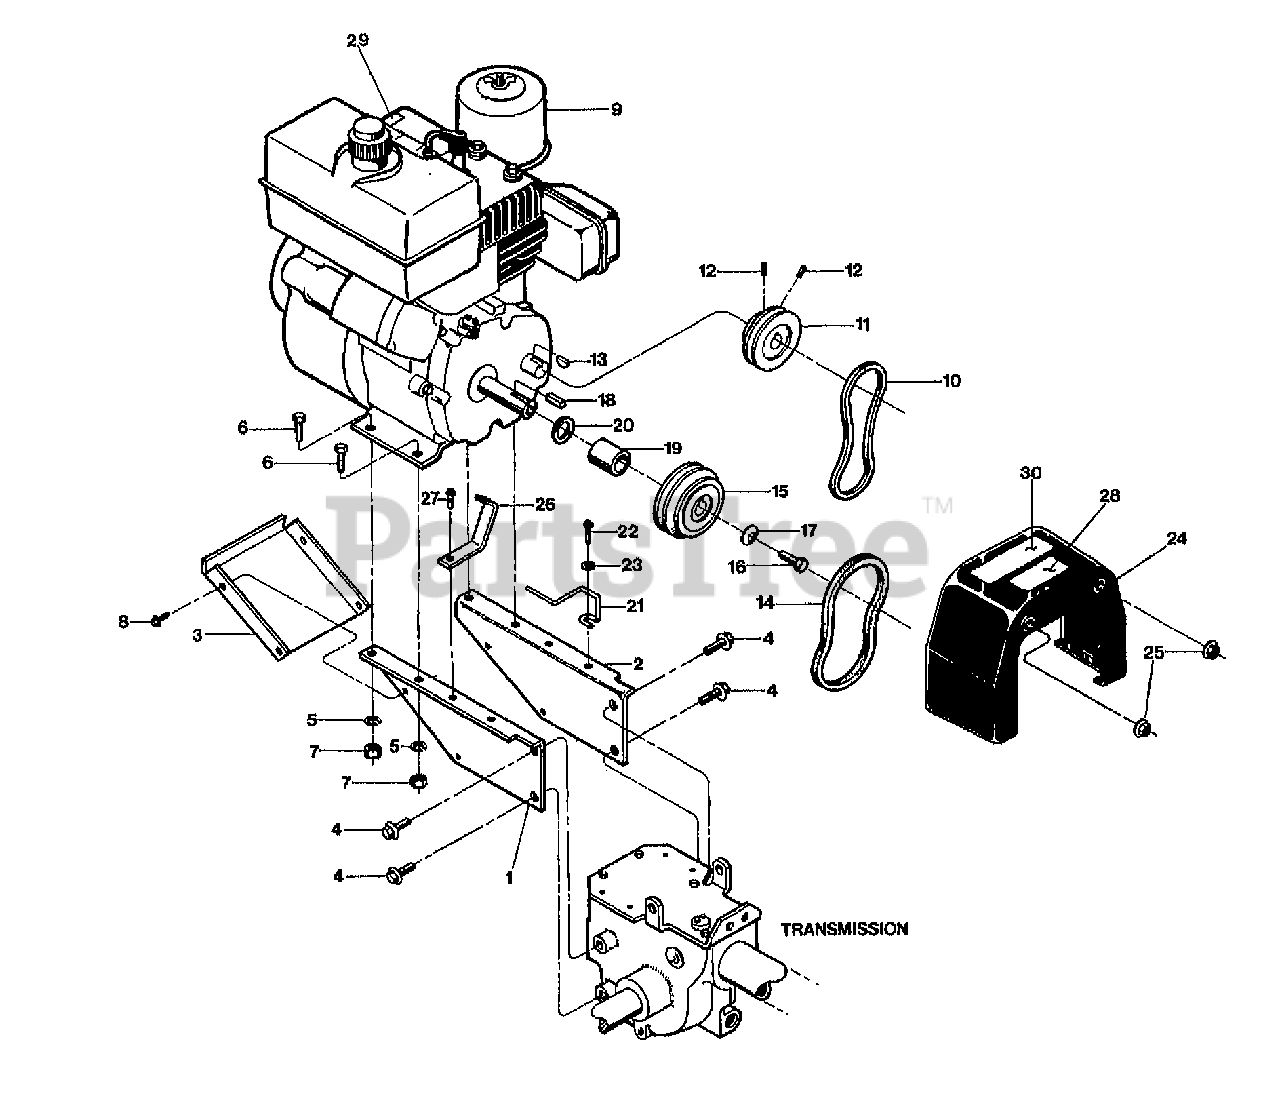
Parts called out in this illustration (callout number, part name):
1	BRKT-ENG LT P4
2	BRKT-ENG RT PNT
3	PAN-ENG BRKT PNT
4	SCR-HFLK 5/16-18X.75 ZP
5	WASHER-LK .312 ZP
6	SCR-HHC 5/16-18X.75 GR 5 ZP
7	NUT-HEX 5/16-18 ZP
8	SCR-HH SEMS 10-32x.5 ZP (W/PERMANENT WASHER)
9	ENGINE, TECUMSEH, 6HP RECOIL START,
10	BELT-V REV DR ECONO (SEE V-BLET SET BELOW)
11	PULLEY-REV MACH
12	SCR-SS 1/4-20 X .25 (SECURES REVERSE ENGINE PULLEY)
13	KEY-WOODRUFF #5
14	BELT-V GROOVE FWD SMFRAME (SEE V-BELT BELOW)
15	PULLEY-ENGINE MACH
16	SCR-HH 3/8-24X1.0 G5 ZP
17	WASHER-.994X.413X.145
18	KEY-.188 SQX1.0
19	SPACER-.937X.755X.938
20	SHIM-1.0X.7656X.031
21	GUIDE-BELT FWD
22	SCR-HWH 1/4-20 X .75 STH
23	WASHER-FLAT 1/4 SAE
24	COVER-BELT W/DECALS (INCL. 28 & 30)
25	NUT-HFLK 5/16-18 ZP (WHIZ-STYLE)
26	GUIDE-BELT REV PNT
27	SCR-HWH 1/4-20 X .5 STH
28	DECAL-BELT POSITION
29	DECAL-STARTING STABIL
30	DECAL-BELT COVER OPC
